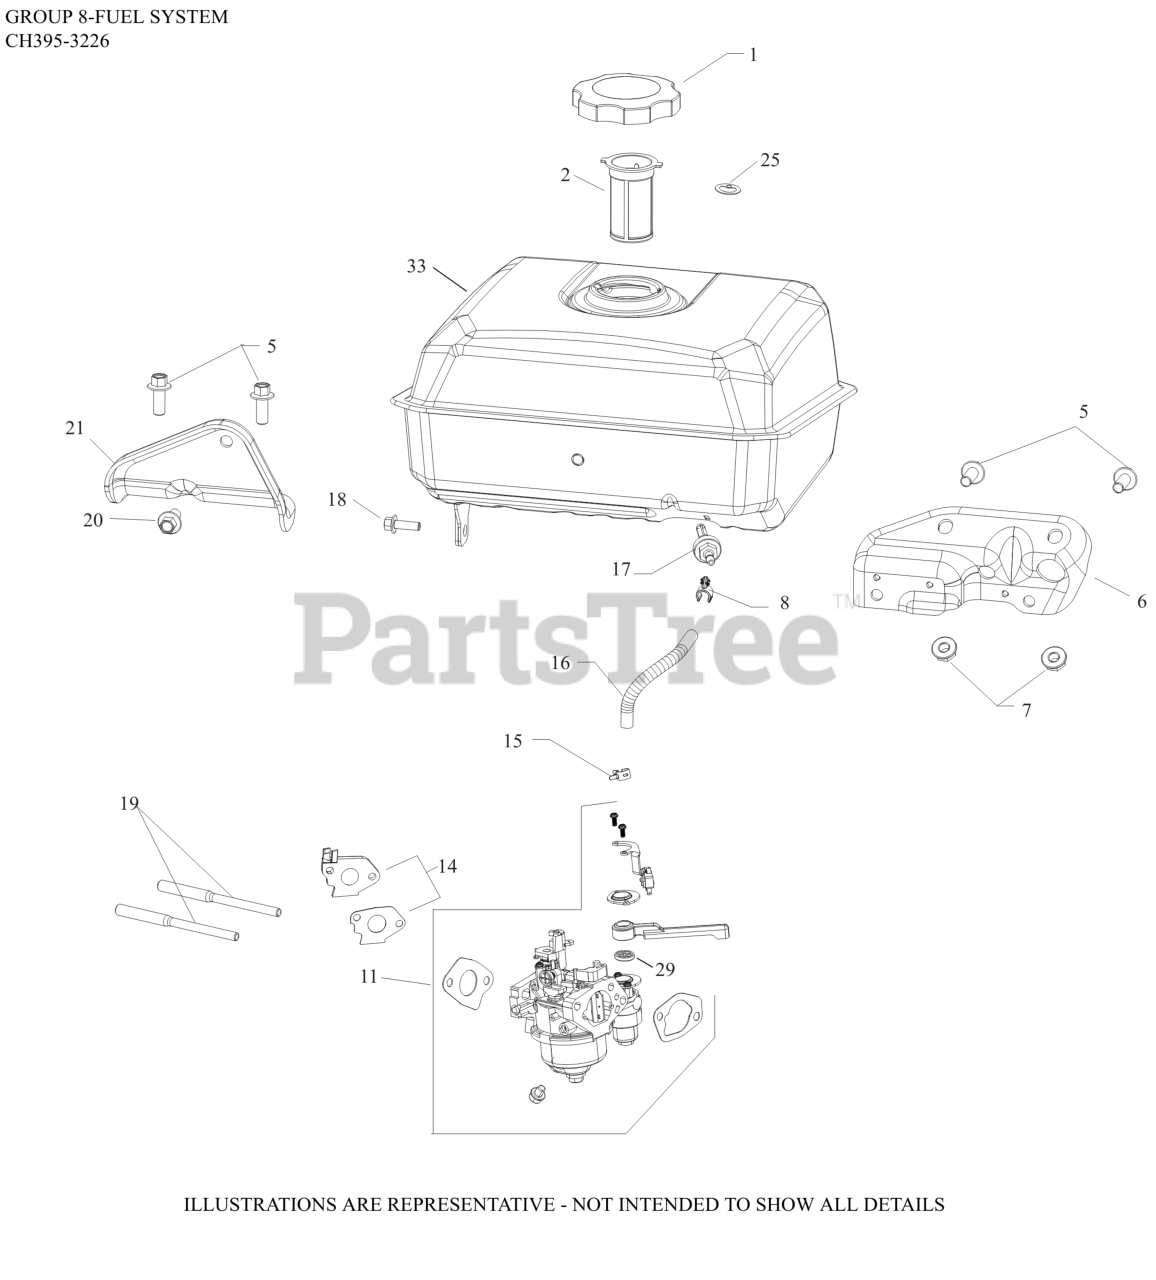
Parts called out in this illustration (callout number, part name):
1	CAP, FUEL TANK
2	FILTER, FUEL TANK
5	SCREW, M8 X 20
6	BRACKET, FUEL SUPPORT ASSEMBLY
7	NUT, FLG M8X1.25
8	CLIP, FUEL HOSE
11	KIT, CARBURETOR COMPLETE
14	INSULATOR AND GASKET KIT
15	CLAMP, FUEL LINE
16	LINE, FUEL (10"-CUT TO LENGTH)
17	FITTING, FUEL ASSY
18	SCREW, M6 X18
19	STUD, CARBURETOR
20	SCREW, FLG 8X1.25X16
21	BRACKET, FUEL SUPPORT
25	KIT, FUEL SCREEN
29	SEAL, INLET VALVE
33	TANK, FUEL
NI	TOOL, SPARK PLUG WRENCH ASSY
NI	KIT, HIGH ALTITUDE (4,000-8,000 FT)
NI	KIT, HIGH ALTITUDE (ABOVE 8,000 FT.)
NI	KIT, CARBURETOR REPAIR
